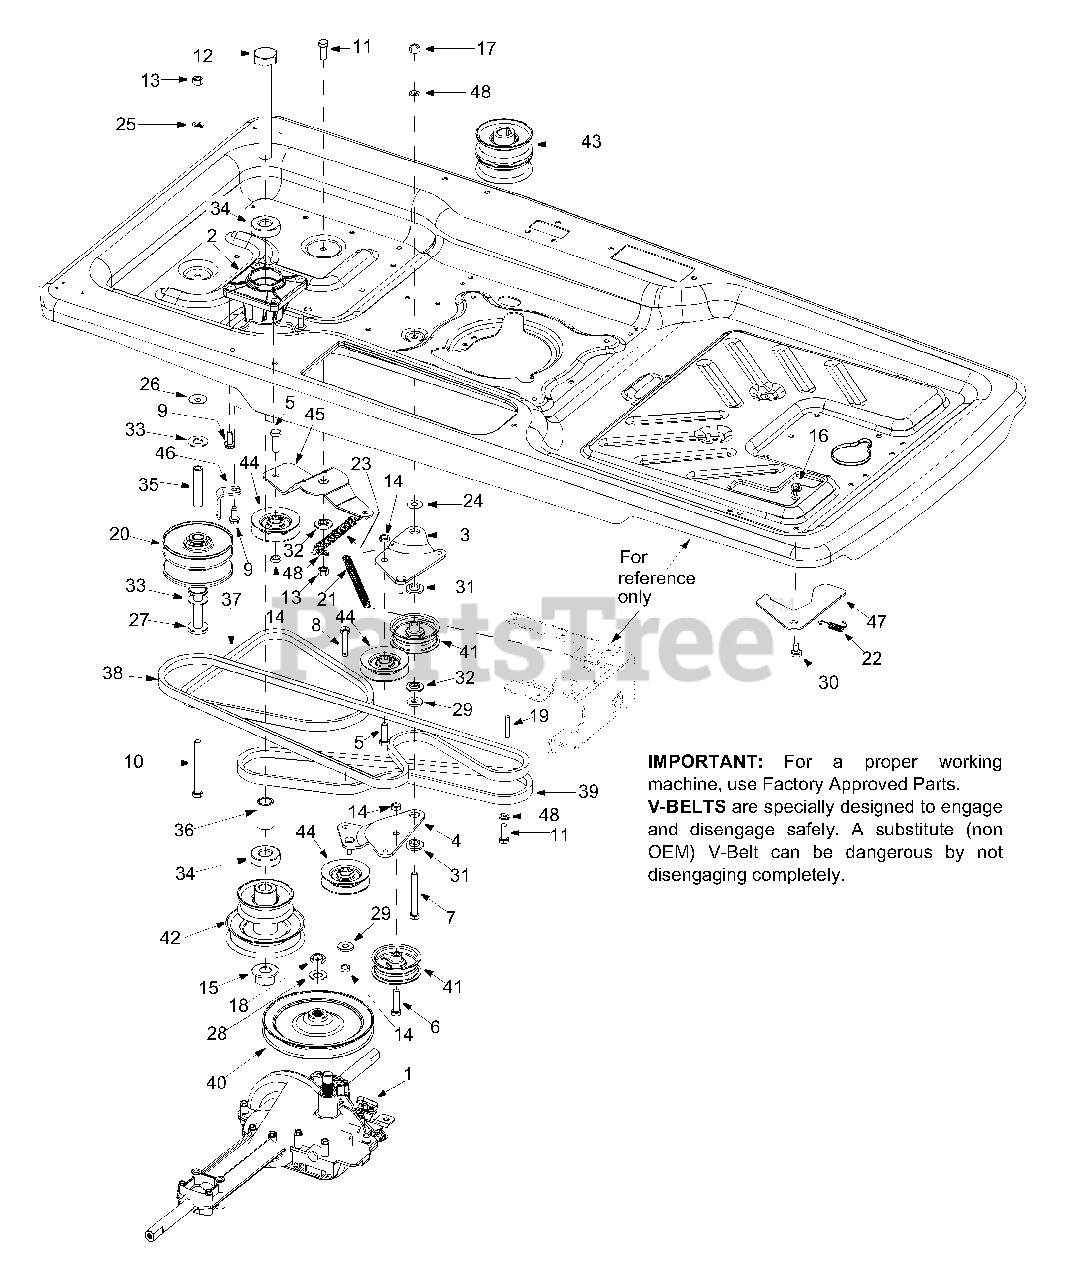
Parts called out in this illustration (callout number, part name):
1	Transmission Assembly
2	Spindle Housing
3	Idler Bracket Assembly
4	Idler Bracket Assembly
5	Hex Bolt 3/8-24 x 1.25"
6	Hex Bolt 3/8-24 x 1.50"
7	Hex Bolt 3/8-16 x 3.0"
8	Hex Bolt 3/8-24 x 1.75"
9	TT Screw 5/16-18 x 0.875"
10	Hex Screw 3/8-24 x 3.75"
11	Hex Screw 3/8-24 x 1.0"
12	Hex Screw M20 x 2.5:180
13	Hex Nut 3/8-24
14	Jam Lock Nut 3/8-24
15	Hex Flange Nut M20 x 2.5
16	Flange Lock Nut 5/16-18
17	Hex Nut 3/8-16
18	Jam Nut 9/16-18
20	Variable Speed Pulley Assembly
21	Extension Spring
22	Extension Spring
23	Extension Spring
24	Flat Washer .406 x 1.0 x .030
25	Lock Washer 3/8
26	Bell Washer .39 x 1.13 x .062
27	Flat Washer 3/8 x 1.25"
28	Bell Washer .567 x 1.125 x .06
29	Flat Washer .406 x 1.0 x .105
30	Shoulder Screw
31	Shoulder Spacer
32	Shoulder Spacer
33	Thrust Bearing
34	Ball Bearing
35	Sleeve Spacer
36	Spacer
37	Belt: V Type
38	Belt: V Type
39	Belt: V Type
40	Transmission Pulley
41	Flat Idler Pulley
42	Jack Pulley: Double
43	Engine Pulley: Double
44	Idler Pulley
45	Idler Bracket: Variable Speed
46	Cable Bracket
47	Bracket: Lock: Pedal
48	Lock Washer 3/8
